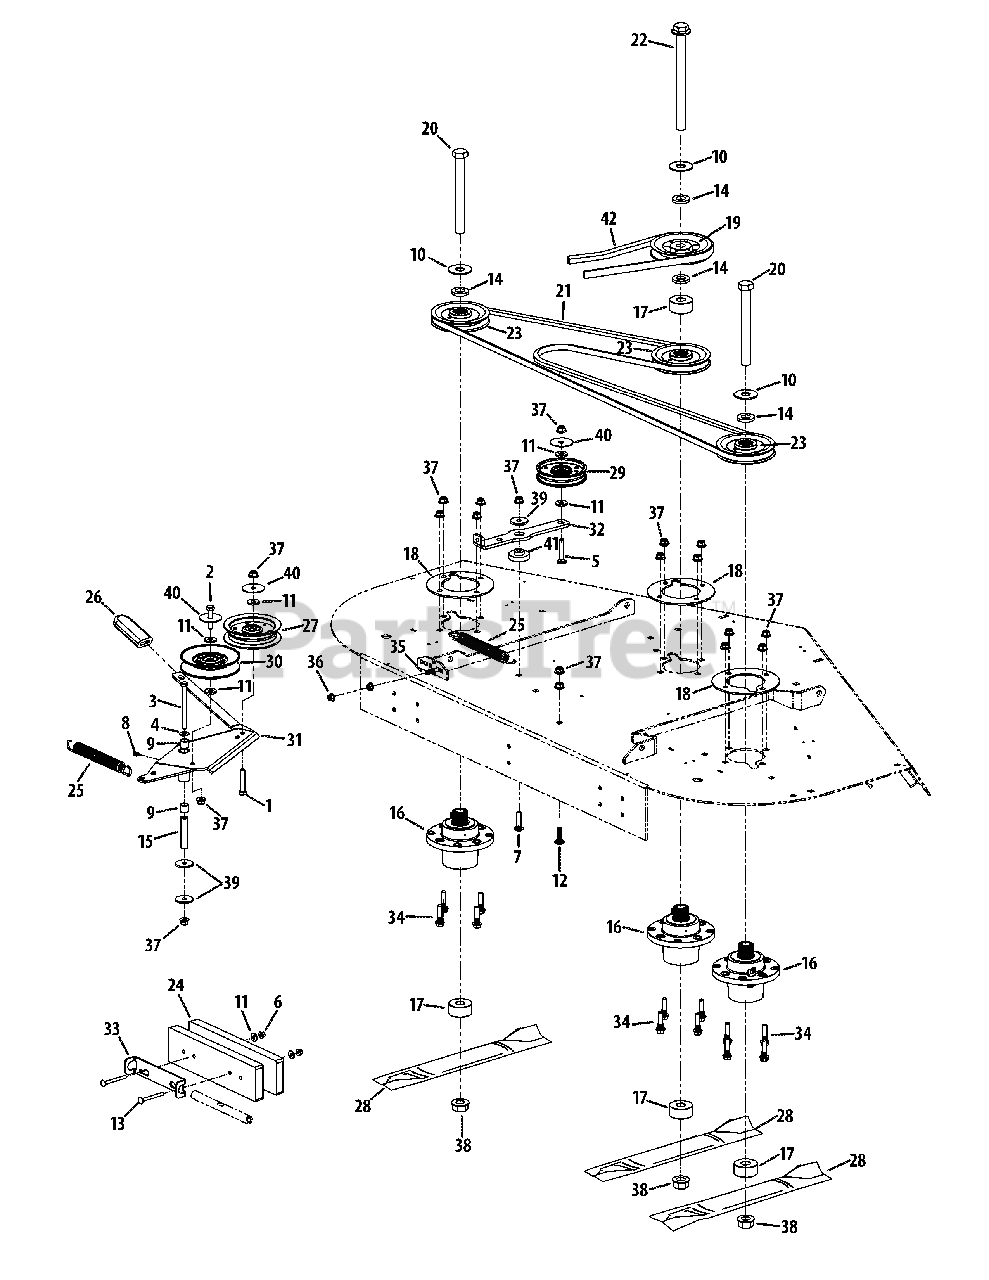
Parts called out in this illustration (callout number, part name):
1	Hex Screw, 3/8-16 x 2.00
2	Hex Screw, 3/8-16 x 1.75
3	Hex Screw, 3/8-16 x 4.00
4	Washer, .406 x .813 x .063
5	Carriage Bolt, 3/8-16 x 2.00
6	Flange Counter Lock Nut, 3/8-16
7	Carriage Bolt, 3/8-16 x 1.50
8	Grease Fitting, 1/4-28
9	Sleeve Bearing, .628 x .753 x .625
10	Washer, .781 x 2.00 x .105
11	Washer, .406 x 1.00 x .105
12	Carriage Bolt, 3/8-16 x 1.25
13	Carriage Bolt, 3/8-16 x 3.50
14	Spacer, .812 x 1.47 x .218
15	Spacer, .390 x .635 x 2.75
16	Spindle Assembly
17	Spacer, .760 x 2.00 x .925
18	Support Plate
20	Hex Screw, 3/4-16 x 7.00
21	V-Belt, Deck
22	Hex Screw, 3/4-16 x 9.00
25	Extension Spring, .94 x 7.57 x .14
26	Flat Grip, 1.0 x 3.2 x .25
27	Idler Pulley
28	Hi-Lift Blade, 21.0
29	Idler Pulley
30	Idler Pulley
31	Double Idler Handle
32	Deck Idler Arm
33	Weight Bar Bracket
34	Carriage Bolt, 5/16-18 x 1.50
35	Hex Flange Bolt, 3/8-16 x 1.5
36	Flange Lock Nut, 5/16-18
37	Flange Lock Nut, 3/8-16
38	Flange Lock Nut, 3/4-16
39	Flat Washer, .390 x 1.500 x .134
40	Flat Washer, .406 x 1.92 x .060
41	Shoulder Spacer, .854 x .280
